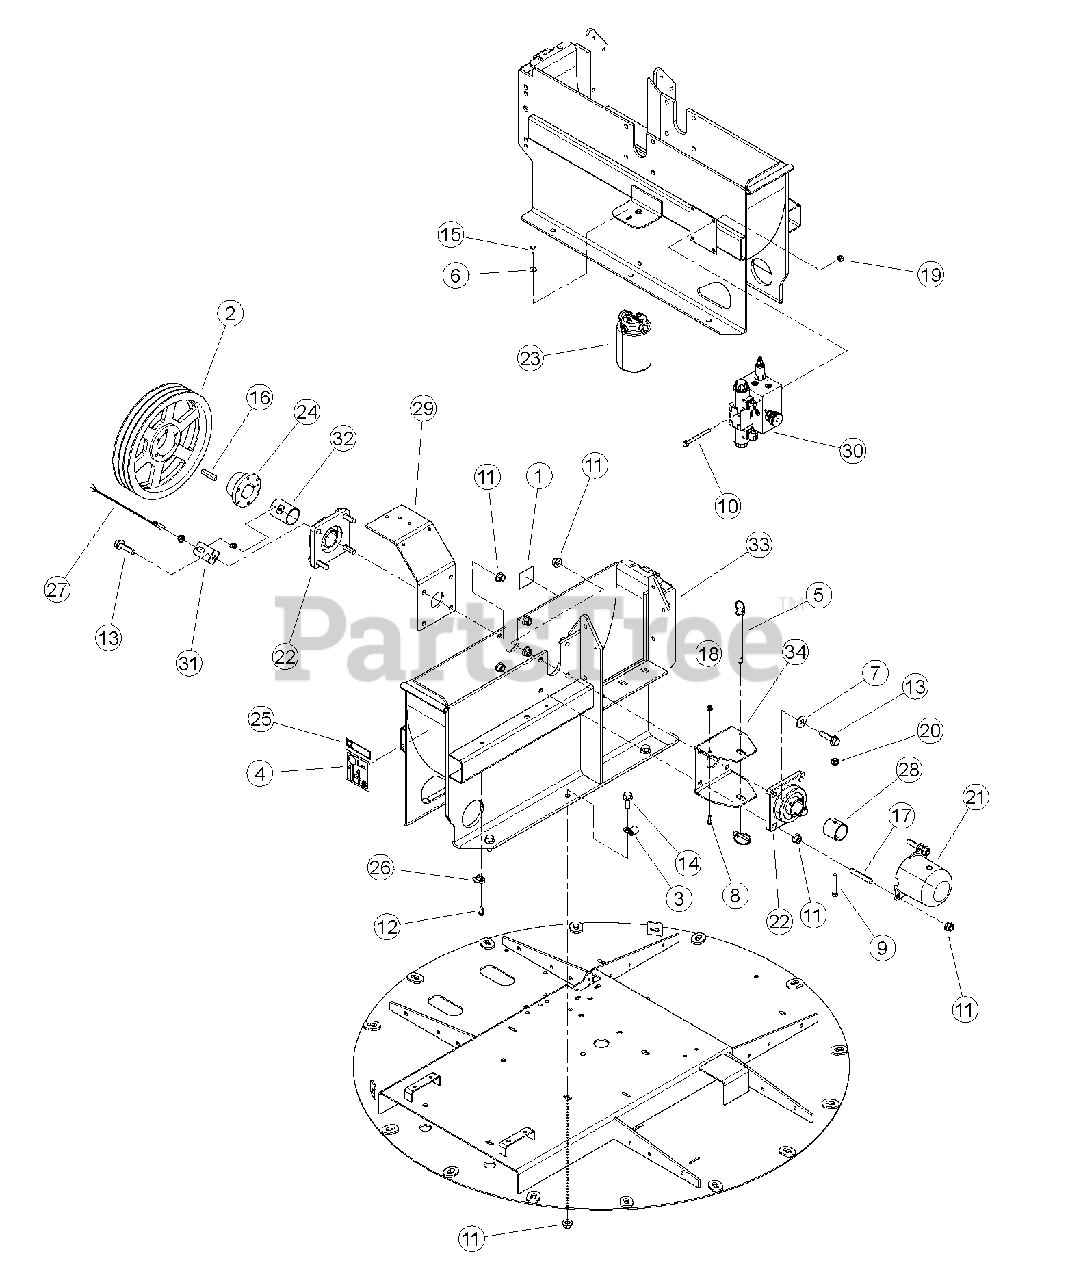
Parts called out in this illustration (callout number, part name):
1	DECAL, SHIELD DANGER ISO
2	SHEAVE, 3BQ12.4, SK
3	CLAMP, 9/16 COATED
4	DECAL, 114 DB (CE COMPLIANT ONLY)
5	PIN, HITCH 1/2 X 6-1/2 W/ LYNCH
6	WASHER, 1/4" FLAT ZP
7	WASHER, 1/2" FLAT ZP
8	BOLT, 1/4-20X3/4 HWH GR5 CZP
9	BOLT, 3/8 X 2-1/2 GR5 HHCS ZP
10	BOLT, 5/16 X 3-1/2 SERRATED FLANGE NC
11	NUT, 1/2-13 NYLOCK FLANGE
12	SCREW, 11/32 X 7/8 HWH AB THREAD ZP
13	BOLT, 1/2-13 X 2 HWH GR5 CZP
14	BOLT, 1/2 -13 X 1-1/4 FLANGE NC
15	BOLT 1/4 X 5/8" HHCS GR5 ZP
16	KEY, 3/8" SQ X 2" LG PLAIN
17	STUD, 1/2"-13 X 3" LG B7 ZP
18	NUT, 1/4-20 NYLOCK-FLANGE
19	NUT, 5/16-18 NYLOCK-FLANGE
20	NUT, 3/8-16 NYLOCK FLANGE
21	CAP, LARGE SHAFT
22	BEARING, 1-3/4 4 BOLT FLANGE
23	ASSEMBLY, HYDRAULIC FILTER
24	BUSHING, SK 1-3/4"
25	DECAL, 76835 INFORMATION (CE COMPLIANT ONLY)
26	CLAMP, CABLE MOUNT
27	SENSOR, M12 PNP PROXIMITY (REPLACEMENT PART)
28	COLLAR, CHIPPER LOCK
29	WELDMENT, REAR GUARD SUPPORT
30	ASSEMBLY, HYDRAULIC FEED FLOW VALVE W/ PS
31	BRACKET, PROXIMITY SENSOR
32	WELDMENT, SPACER 2.0 X 2.30
33	WELDMENT, CHIPPER BOTTOM
34	BRACKET, ROTOR LOCK
